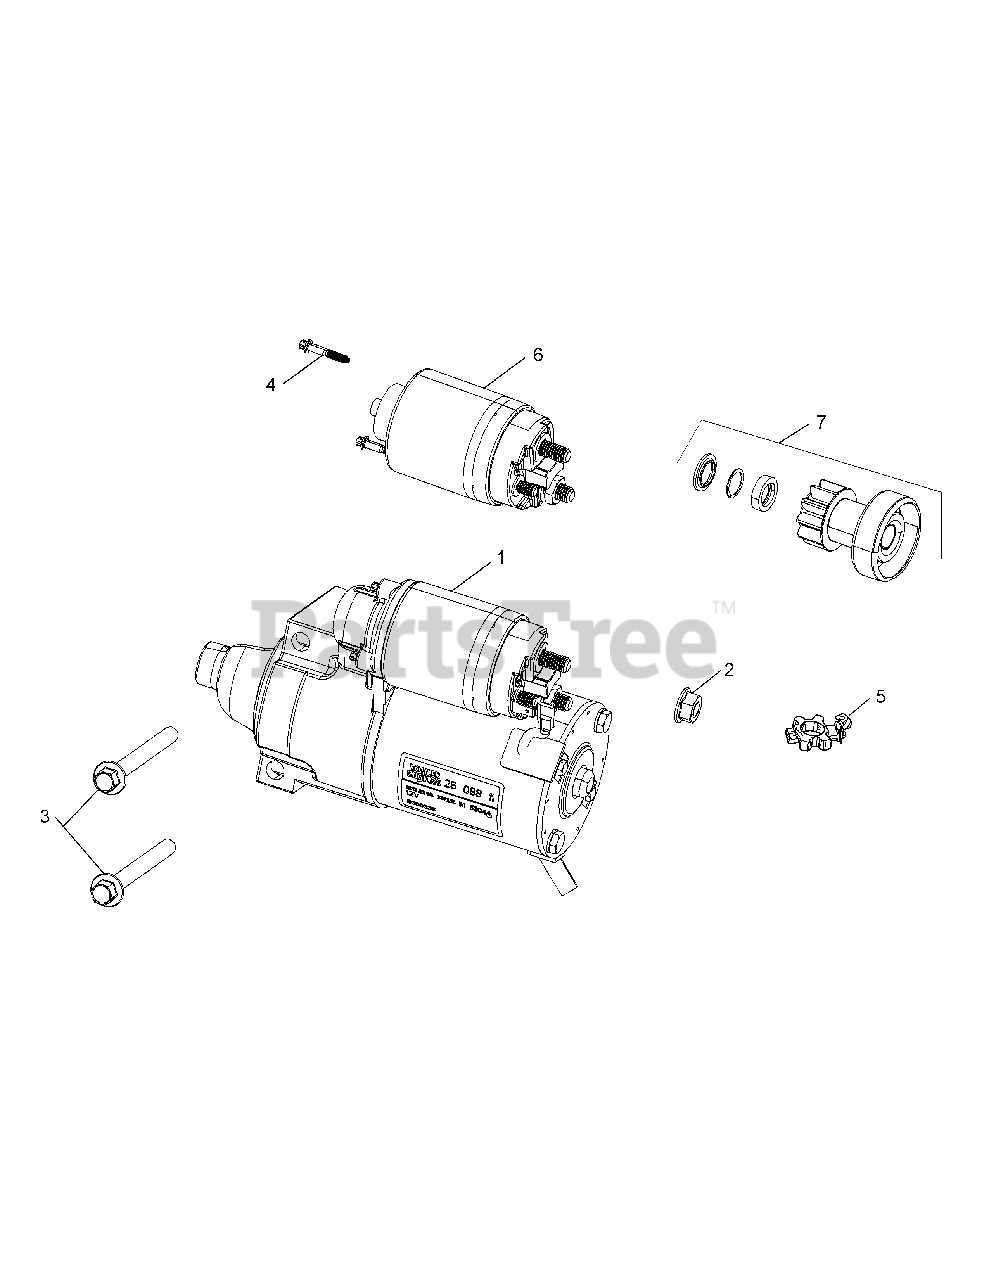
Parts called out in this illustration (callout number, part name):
1	Solenoid Shift Starter Assembly
2	Flange Nut, M8x1.25
3	Flange Screw, M8 x 1.25 x 80
4	Torx Head Screw
5	Brush Holder Kit
6	Solenoid Kit (Inc. 4)
7	Starter Pinion Kit
